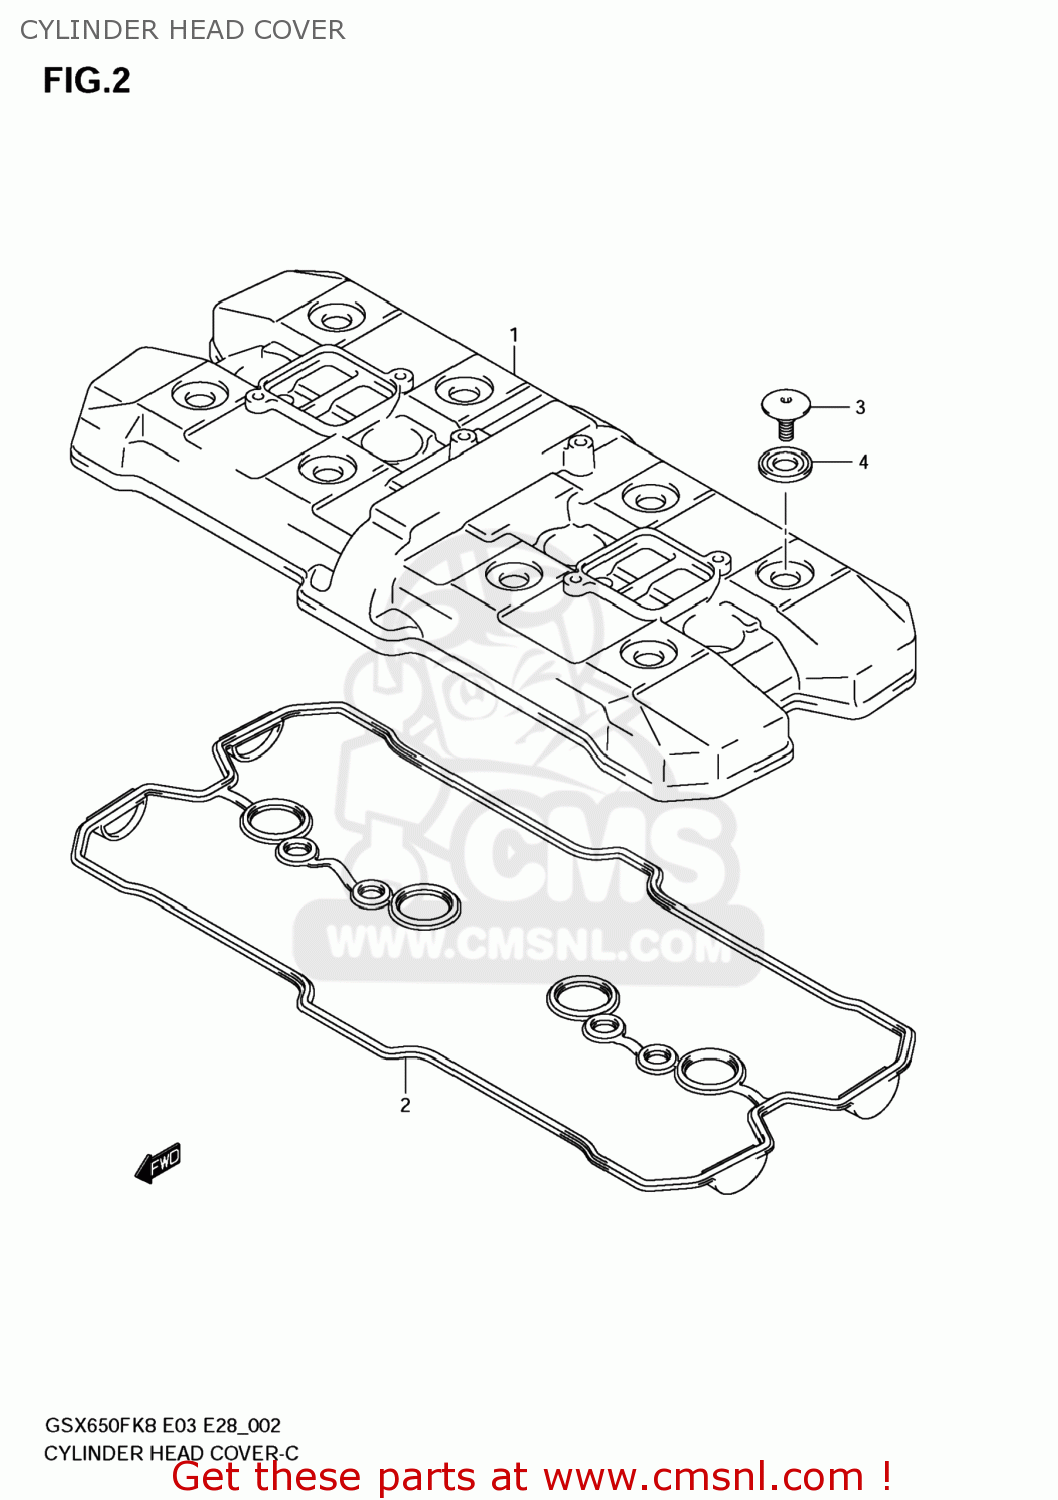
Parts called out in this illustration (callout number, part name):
1	COVER,CYLINDER HEAD
2	GASKET,CYL HEAD COVER (NAS)
3	BOLT(7X17.5)
4	WASHER,CYL HEAD COVER
